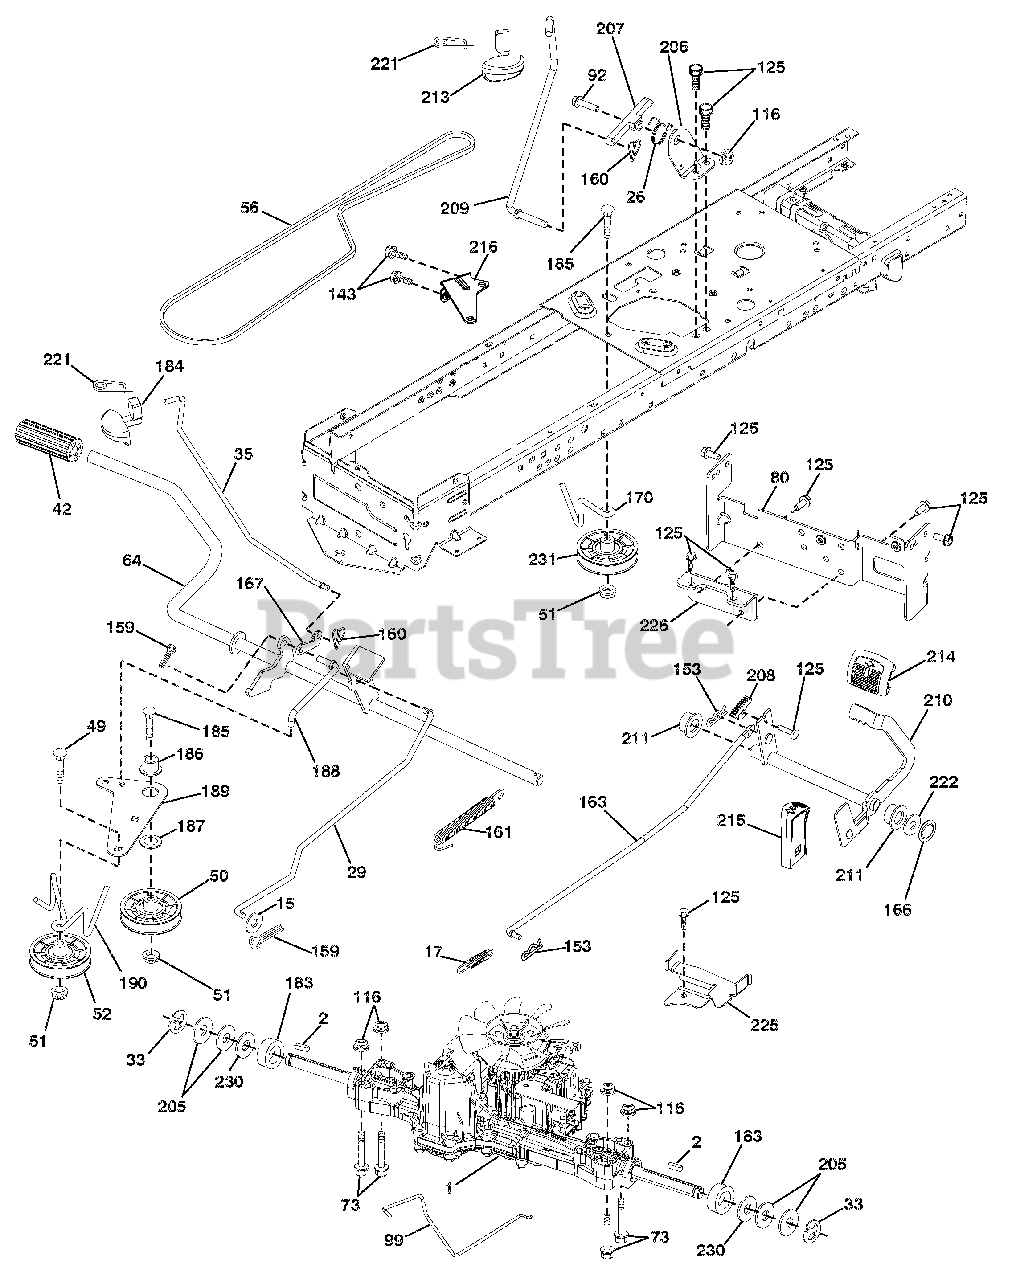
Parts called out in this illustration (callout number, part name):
1	TRANSAXLE, TUFFTORQ K46BT(ORDER PARTS FROM TRANSAXLE MANUFACTURER)
2	KEY.SQUARE.2.0 X .1845/.1865
15	WASHER.13/32 X 13/16 X 16 GA.
17	SPRING.BRAKE.K46.GREEN
26	SPRING.RETURN.CRUISE
29	ROD.BRAKE.K46
33	E-RING.#5133-75
35	ROD.BRAKE.PARKING.LT.TEX
42	COVER.PEDAL.BLK.ROUND
49	BOLT.RDHD.3/8-16UNCX1-3/4.GR5
50	IDLER.FLAT.910"OFFSET
51	Nut, Hex, Flangelock 3/8-16
52	IDLER.V-GROOVE.910"OFFSET
56	V-BELT.MOWER.92.40.42/K46
64	SHAFT ASM.PEDAL.BRK.CNTRL.PCH
73	BOLT.HEX.FLGHD.5/16-18.GR.5
80	STRAP.TORQUE.K46/18"TEX
92	Bolt, Hex Head 5/16-18 x 1-1/4
99	ROD.SPRING.BYPASS.K46.LT.Z
116	Nut, Lock Hex Flange 5/16-18 u
125	SCREW.5/16-18X3/4.SMGML.TAP/BL
143	SCREW.THDROL.5/16-18 X 1/2TYTT
153	Retainer Spring
159	PIN.COTTER.1/8 X 3/4.CAD.
160	RETAINER.CLIP(M).DIA.290
161	SPRING.RETURN.CLUTCH.6.75
163	ROD.CONTROL.PEDAL.K46
166	NUT PUSH .625
167	LATCH.BRAKE.PARKING
170	KEEPER.CENTER SPAN.1.688
183	SPACER.AXLE.HYDRO/PEERLES
184	HANDLE.PARKING BRAKE.LTTEX.505
185	BOLT.RDHD.3/8-16UNC X2-3/4 GR5
186	SPACER.RETAINER
187	WASHER.13/32 X 2 X 10 GA.
188	LINK.CLUTCH.GROUND DRIVE
189	BELLCRANK.GROUNDRIVE.NSTG/NSTL
190	KEEPER.BELLCRANK.DRIVE.GROUND
205	WASHER.25/32 X 1-5/8 X 16GA.
206	BRACKET.MOUNT.LATCH.CRUISE
207	LATCH.CONTROL.CRUISE
208	GEAR SECTOR.CONTROL.CRUISE
209	ROD.CONTROL.CRUISE.LT.ELITE
210	ROCKER ASM.PEDAL CONTROL.TEXLT
211	BEARING.NYLON.BLK..629 ID.
213	HANDLE.CONTROL.CRUISE.ELTE.428
214	PAD PEDAL FORWARD
215	PEDAL.REVERSE.TEX.GT.428
216	BRACKET.PULLEY.IDLER.WTEX
221	RETAINER.SPRING.CLIP.HANDLE
222	WASHER.21/32X1-1/4.10GA.N/PLTD
225	KEEPER.BELT.TRANSAXLE.K46
226	BRACKET.MOUNT.TORQUE.K46.TLT
230	WASHER.HARDEN..793 X 1.637X060
231	IDLER.V-GROOVE.1.688"OFFSET
